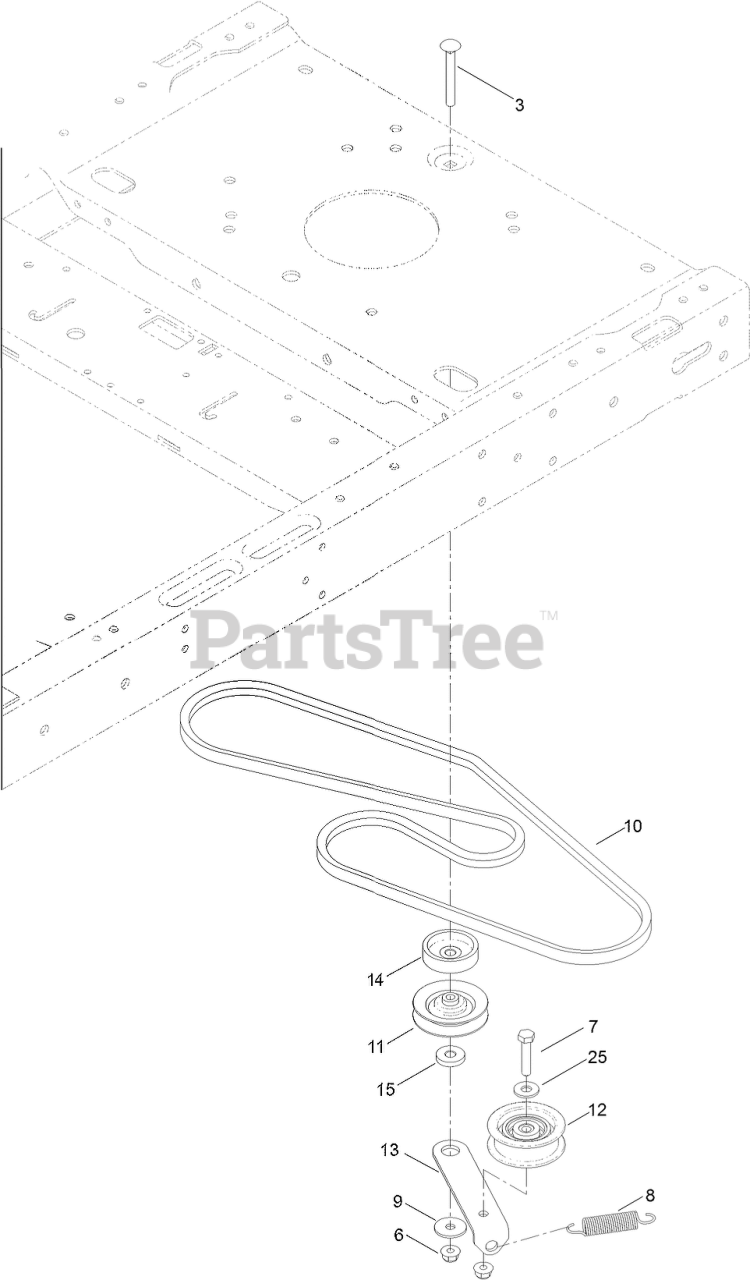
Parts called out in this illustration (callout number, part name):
3	SCREW-CARR
6	NUT-HF, NI
7	SCREW-HH
8	SPRING-RETURN, PEDAL
9	WASHER-PIVOT
10	V-BELT
11	PULLEY-IDLER
12	PULLEY-IDLER
13	ARM-IDLER
14	SPACER
15	SPACER-ARM, IDLER
25	WASHER-FLAT
